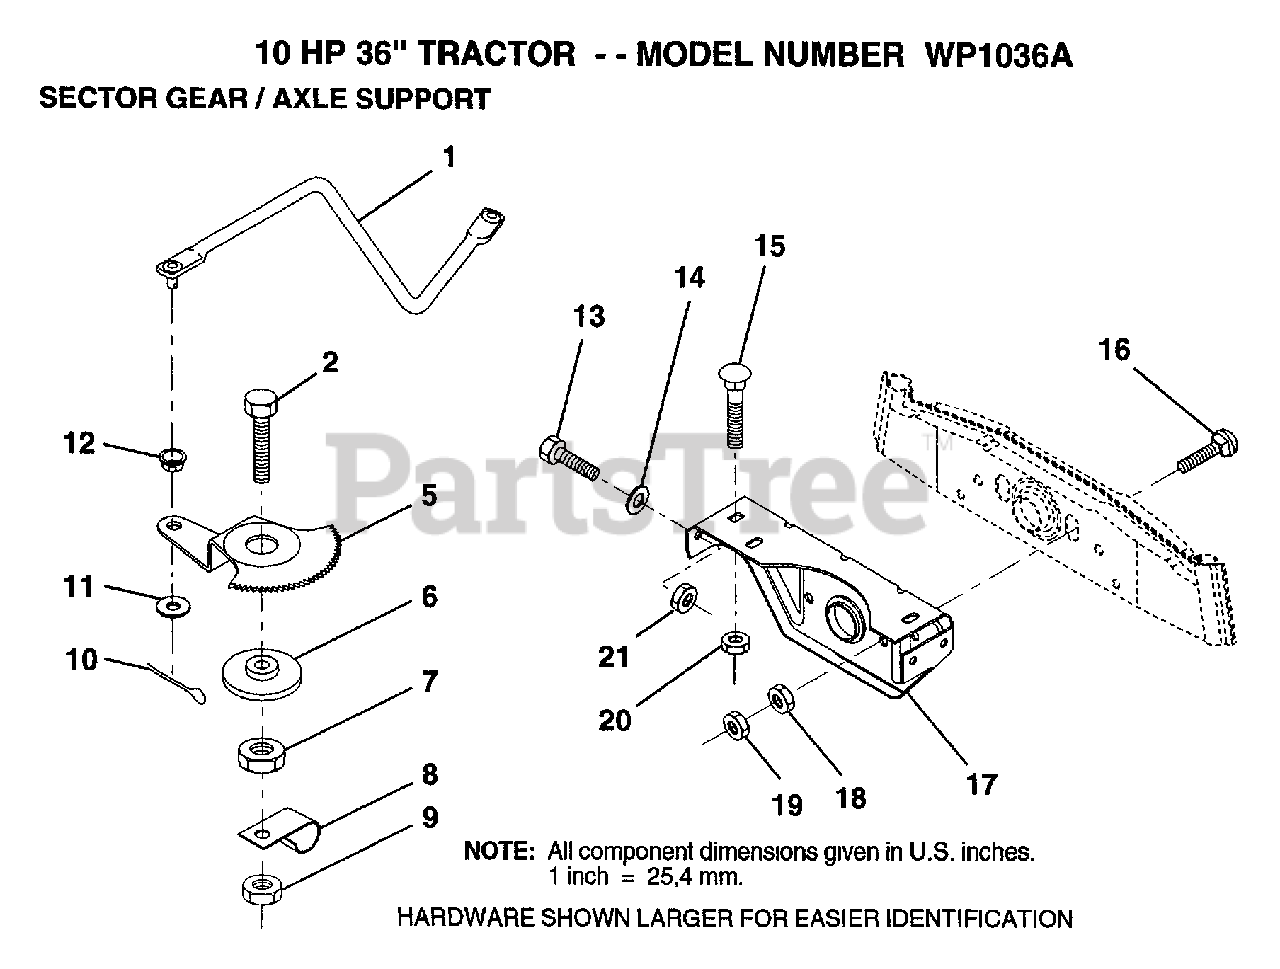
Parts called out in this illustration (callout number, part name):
1	DRAG LINK
2	"BOLT,HEX"
5	GEAR SECTOR
6	BUSHING
7	NUT
8	CLIP INSULATOR
9	NUT LTV
10	COTTER PIN
11	WASHER
12	BUSHING.DRAGLINK
13	BOLT
14	WASHER
15	BOLT
16	BOLT
17	"SUPT,FRT AXLE"
18	NUT.HEX.3/8-16UNC
19	LOCKNUT
